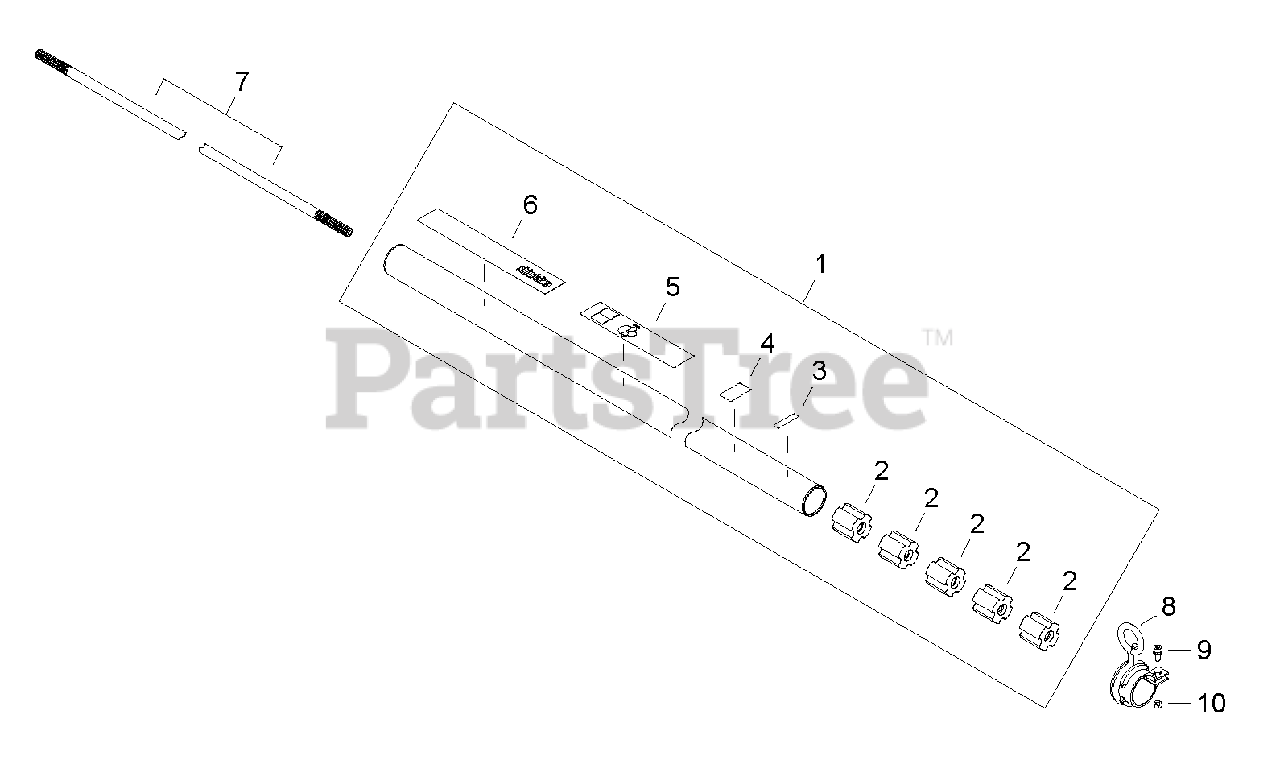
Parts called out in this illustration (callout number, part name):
1	MAIN PIPE ASSY
2	BUSHING
3	LABEL - ALIGNMENT
4	LABEL, HANDLE
5	LABEL, CAUTION (BLADE CAPABLE)
6	LABEL, SHINDAIWA PROFESSIONAL
7	MAINSHAFT
8	HANGER, SWIVEL
9	BOLT M5×12
10	NUT M5
